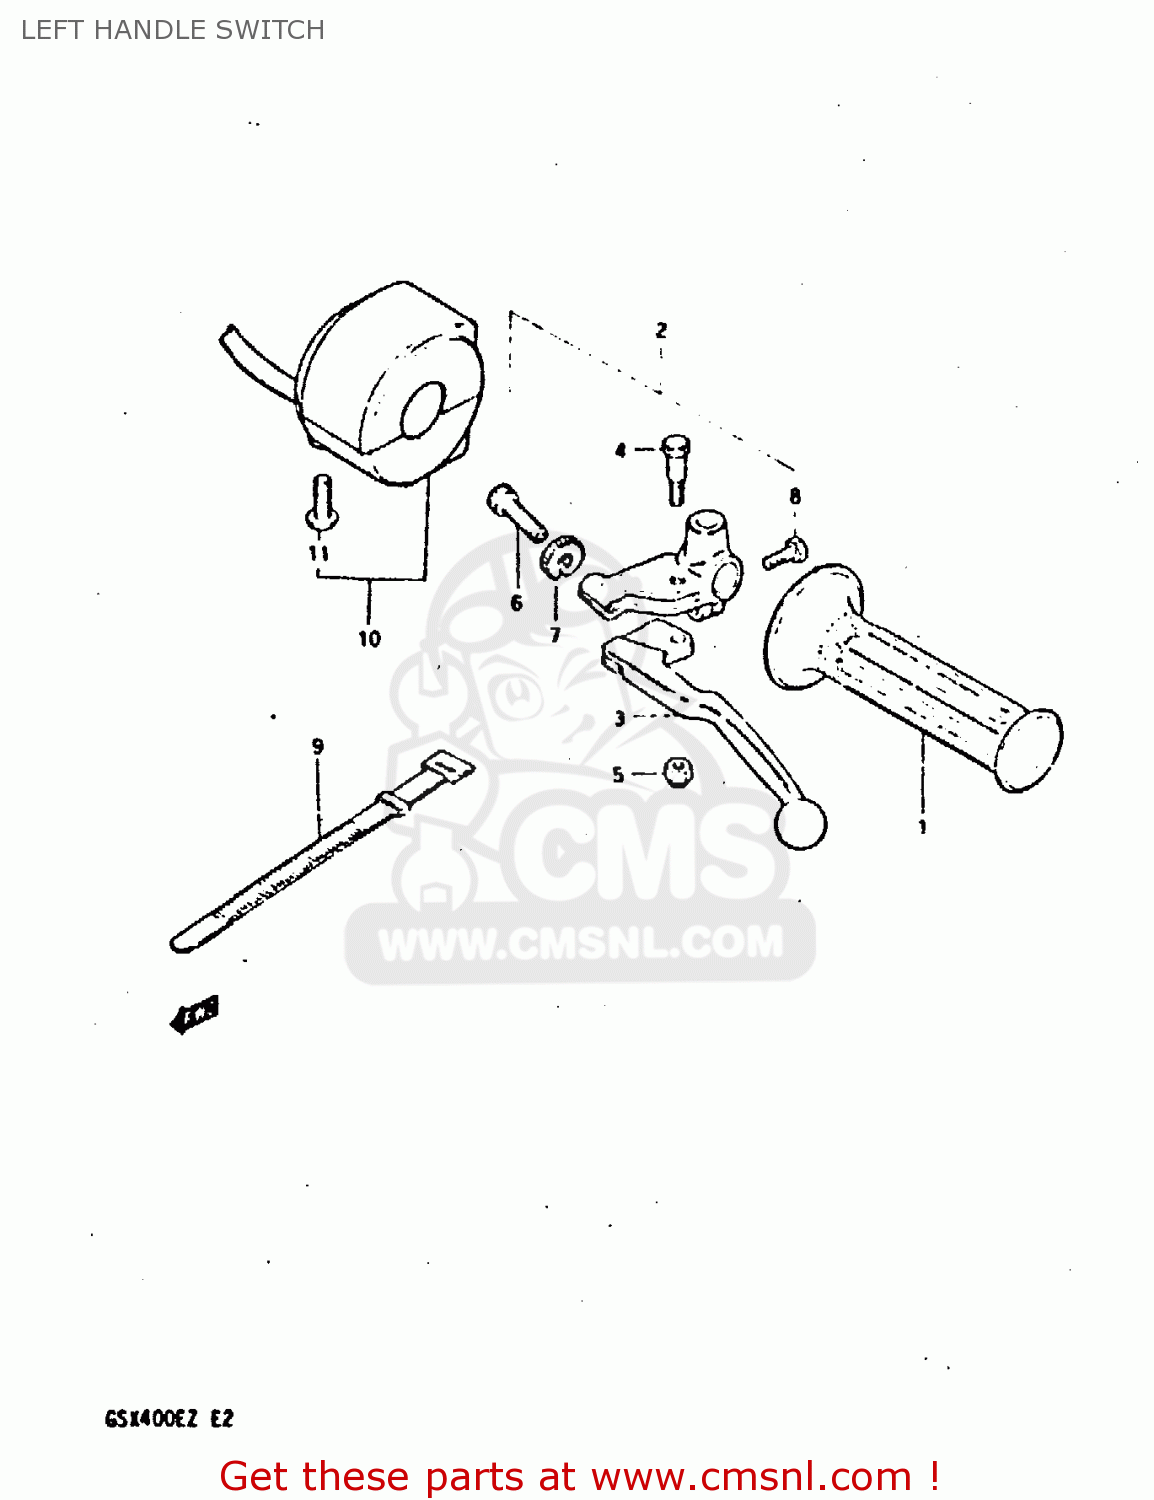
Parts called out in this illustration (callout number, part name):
1	GRIP,LEFT
2	LEVER ASSEMBLY
3	LEVER,CLUTCH
4	BOLT,LEVER
5	NUT 6MM
6	ADJUSTER,CABLE
7	NUT,CABLE ADJUSTER
8	BOLT
9	CLAMP(L:120)
10	SWITCH ASSY, HANDLE LH
11	SCREW
